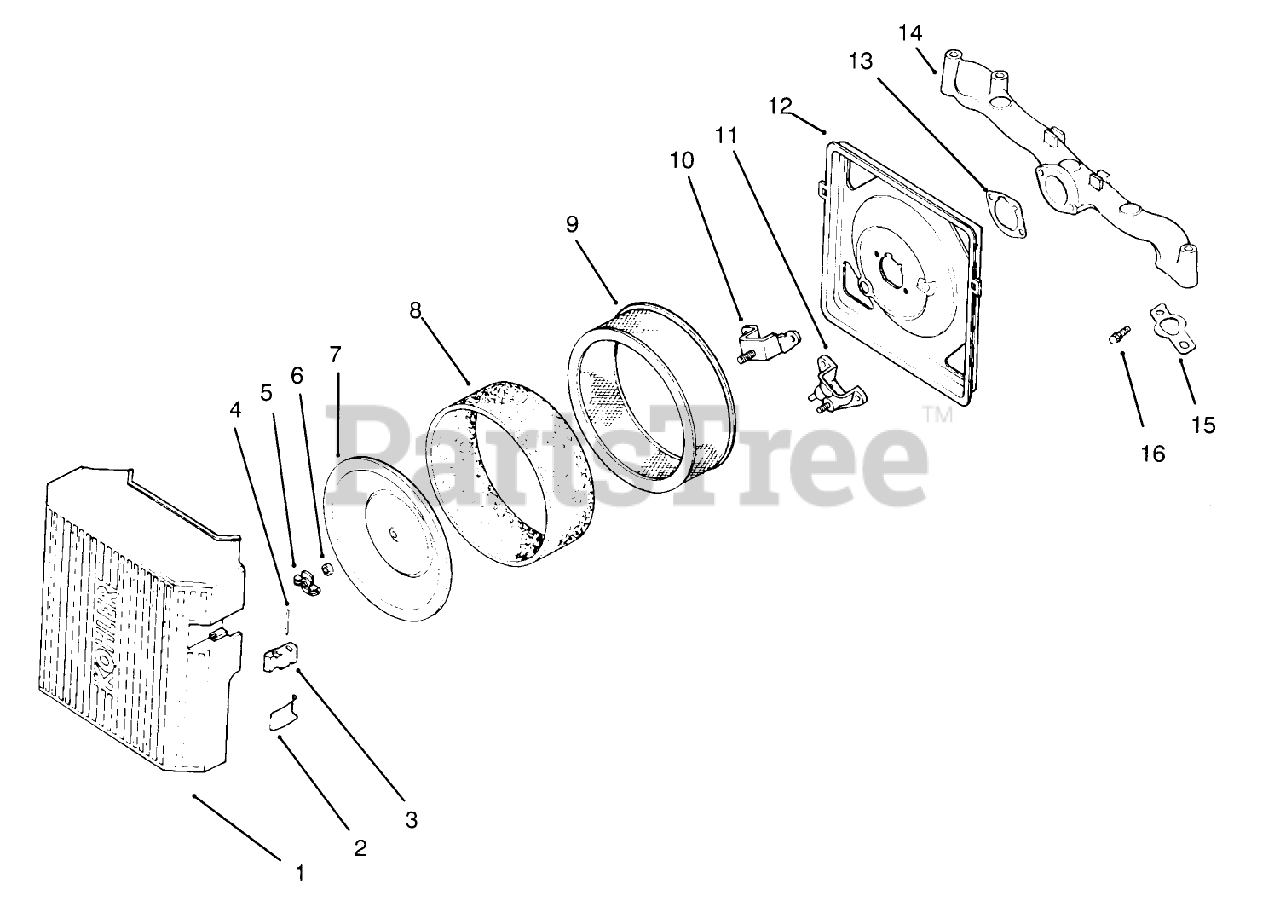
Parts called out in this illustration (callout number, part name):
1	Kit-A/C Cover INCL 2-4 (Only On: 72103;
2	Spring-Latch (Only On: 72103)
3	Latch-Lever (Only On: 72103)
4	Pin-Latch Lever (Only On: 72103)
5	Nut-Wing
6	Seal-Air Intake (Only On: 72103)
7	Cover-Inner Air Cleaner
8	Element-Precleaner
9	Element-Air Cleaner
10	Cup-Fuel Spitback (Only On: 72103)
11	Gasket-Fuel Spitback Cup (Only On: 72103, 72083)
12	Base-Air Cleaner (Only On: 72103)
13	Gasket-A/C Base (Only On: 72103, 72083)
14	Manifold-Intake (Only On: 72103)
15	Gasket-Intake Manifold
